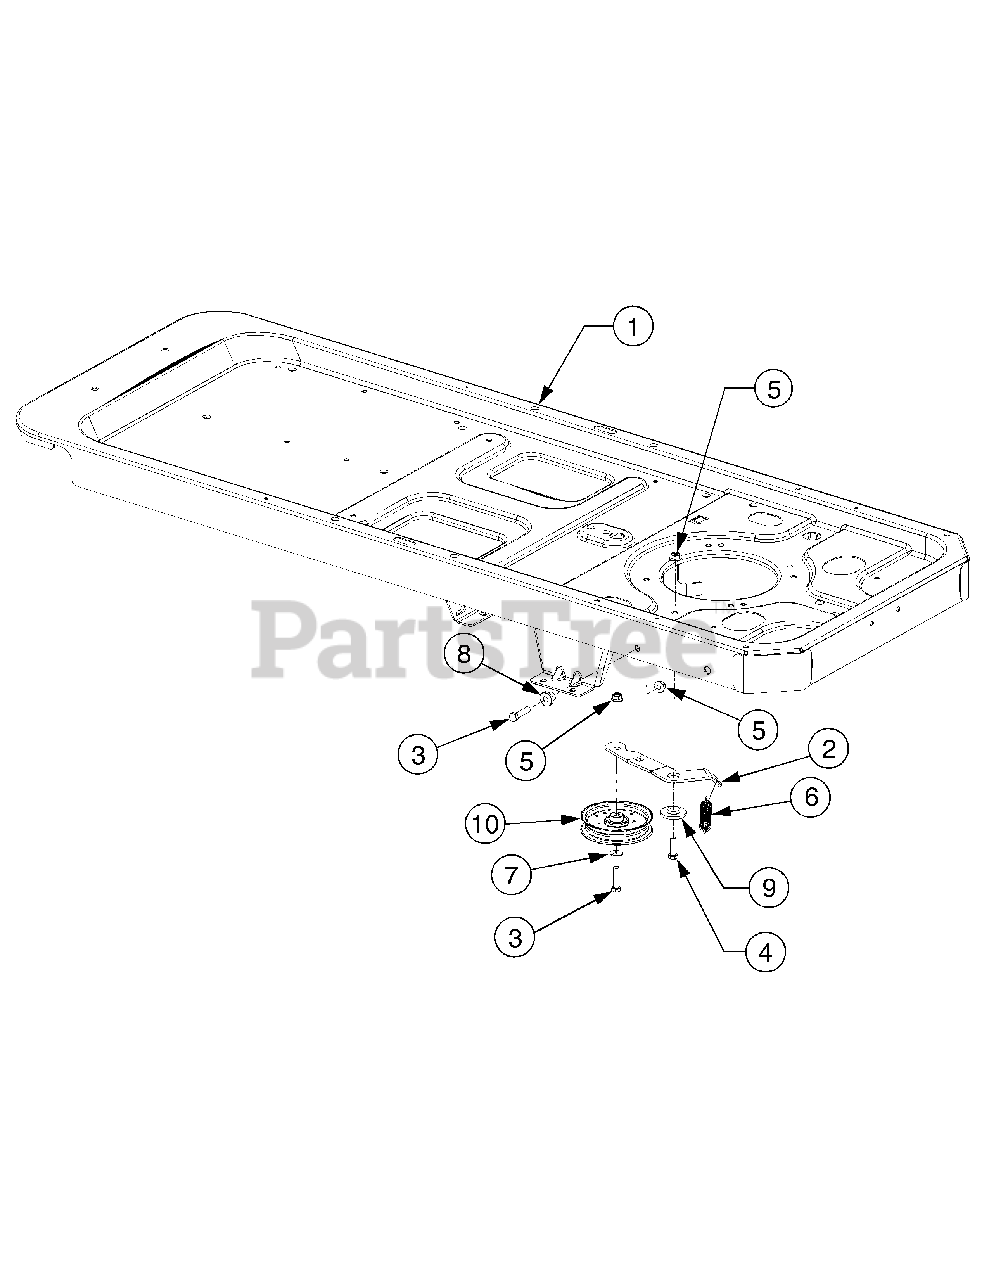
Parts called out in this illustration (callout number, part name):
1	Graphic, Cub Cadet
1	Graphic, Release Lever
3	Screw, Hex Cap, 3/8-16 x 1.5 GR5
4	Screw, Hex Cap, 3/8-16 x 1.25 GR5
5	Nut, Hx Insert Flnge Lck, 3/-16 GrF
6	Spring, Extension, .75 x 5.06
7	Washer, Flat, .408 x .875 x .059
8	Spacer, Shoulder, .39 x 1.0 x .7
9	Spacer, Shoulder, .884 x .19
10	Pulley, Idler, 4.25 Dia.
